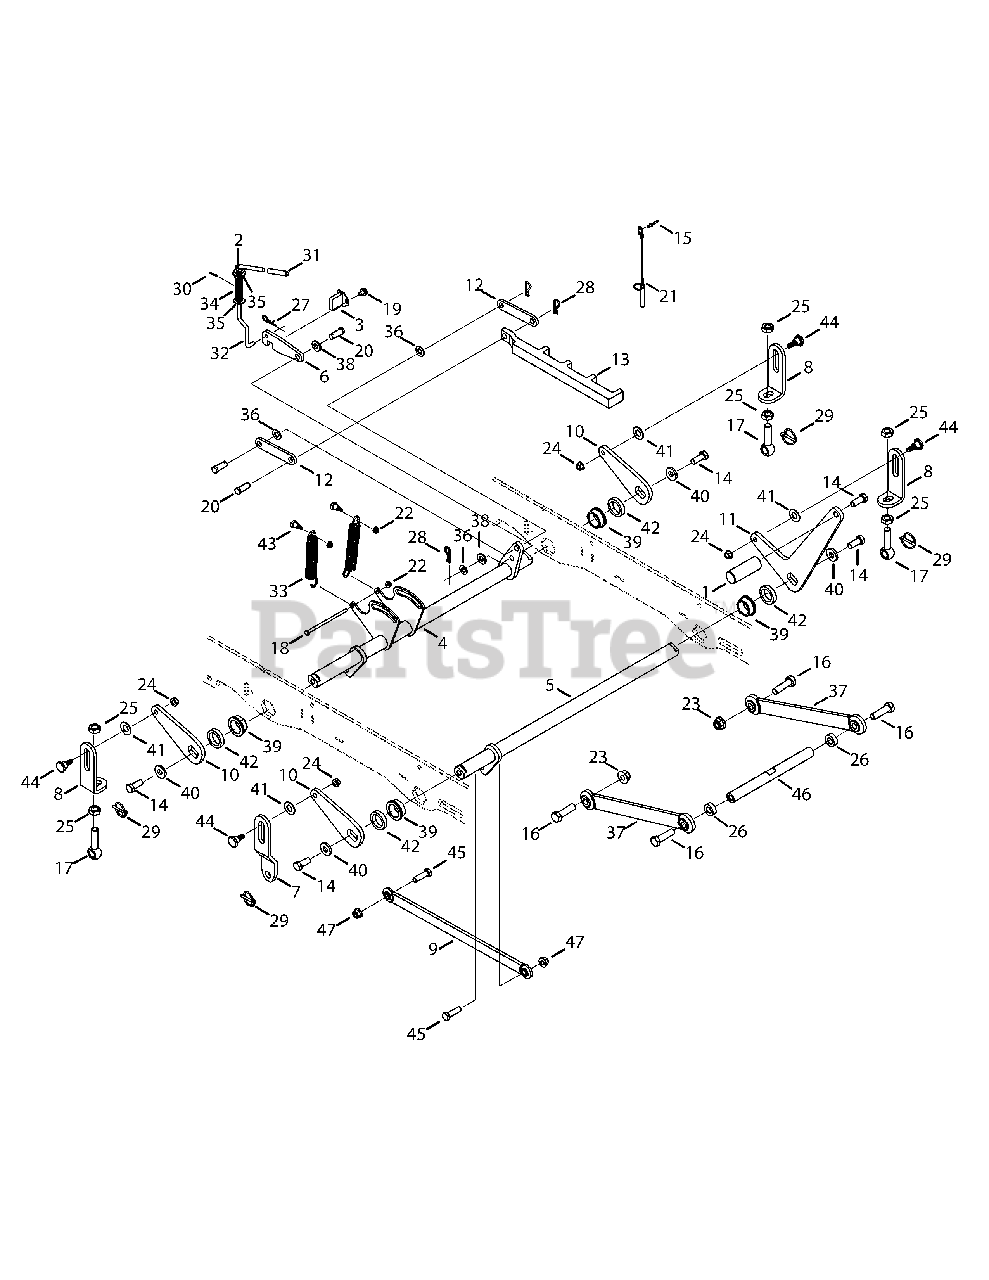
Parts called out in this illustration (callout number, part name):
1	Deck Lift Foot Pedal
2	Bearing, .385 ID
3	Lift Lock Mount
4	Deck Lift Shaft, Rear
5	Deck Lift Shaft, Front
6	Latch Lock Bracket
7	Lift Link Arm
8	Deck Adjustment Lift Link Arm
9	Deck Lift Arm Assembly
10	Deck Lift Bellcrank
11	Deck Lift Foot Pedal
12	Deck Index Link Arm
13	Lift Index Slider Arm
14	Hex Cap Screw, 1/2-13 x 1.25
15	Rivet, 3/16 x .325
16	Hex Cap Screw, 5/8-11 x 2.25
17	Eye Bolt, 5/8-18 x 2.63
18	Hex Cap Screw, 1/4-20 x 5.00
19	Screw, 5/16-18 x .500
20	Clevis Pin, .500 x 1.25
21	Clevis Pin, .438 x 1.5
22	Nut, 1/4-20, Flangelock
23	Nut, 5/8-11, Flangelock
24	Nut, 3/8-16, Flange Centerlock
25	Jam Nut, 5/8-11
26	Spacer, .635 x 1.25 x .445
27	Click Pin, .092 x 1.64
28	Internal Cotter Pin
29	Lynch Pin, .1875
30	Cotter Pin, 3/32 x .750
31	Lift Handle Grip
32	Lift Lock Rod
33	Extension Spring, .969 OD x 6.180
34	Compression Spring, .656 OD x 2.445
35	Bevel Washer, .340 x .872 x .060
36	Washer, .510 x 1.00 x .125
37	Deck Rod Assembly
38	Washer, .510 x 1.00 x .125
39	Hex Flange Bearing
40	Flat Washer, .531 x 2.125 x .250
41	Washer, .640 x 1.25 x .050
42	Spacer, 1.27 x 1.75 x .375
43	Shoulder Screw, .437 x .50, 1/4-20
44	Shoulder Screw, .625 x .442, 3/8-16
45	Hex Cap Screw, 1/2-13 x 1.75
46	Front Lift Link Shaft, Threaded
47	Nut, 1/2-13, Flangelock
